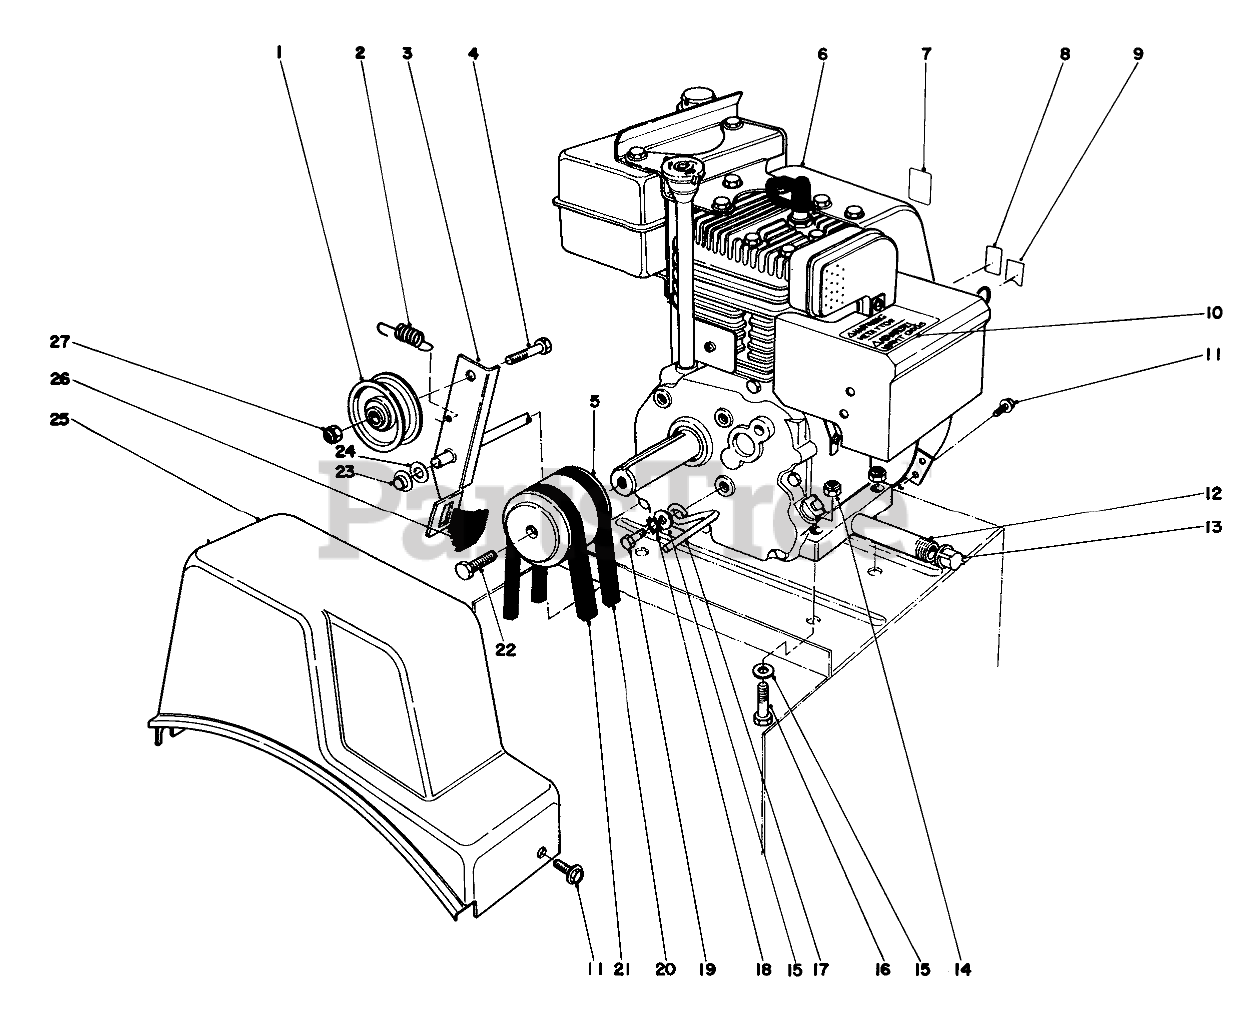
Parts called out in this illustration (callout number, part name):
1	PULLEY-IDLER
2	EXTENSION SPRING
3	Auger Clutch (Incl. Ref. #26)
4	SCREW-HH
5	PULLEY-ENGINE
6	Engine
7	Decal-Primer
8	Decal-Throttle
9	CHOKE DECAL
10	Decal
11	SCREW
12	PIPE NIPPLE
13	CAP-PIPE
14	NUT-LOCK, NI
15	WASHER-PLAIN
16	SCREW-HH
17	RETAINER-BELT
18	WASHER-LOCK
19	SCREW-HH
20	V BELT-3L, TRACTION
21	V-BELT (29.50 INCH)
22	SCREW-SPECIAL
23	RETAINER-PUSH ON
24	WASHER-FLAT
25	COVER-BELT
26	Brake Pad
27	NUT-LOCK, CONE
